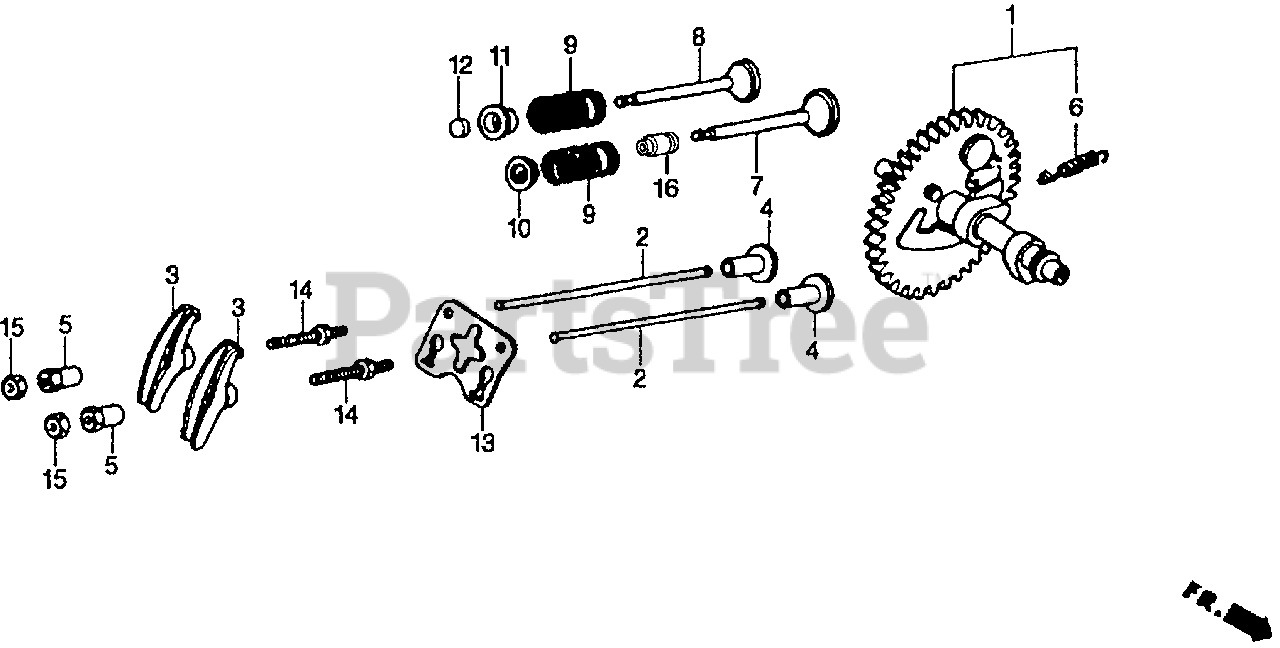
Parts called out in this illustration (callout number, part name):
1	CAMSHAFT ASSY.
2	ROD, PUSH
3	ARM, VALVE ROCKER
4	LIFTER, VALVE
5	PIVOT, ROCKER ARM
6	SPRING, WEIGHT RETURN
7	VALVE, IN.
8	VALVE, EX.
9	SPRING, VALVE
10	RETAINER, IN. VALVE SPRING
11	RETAINER, EX. VALVE SPRING
12	ROTATOR, VALVE
13	PLATE, PUSH ROD GUIDE
14	BOLT, PIVOT (8MM)
15	NUT, PIVOT ADJ.
16	SEAL, VALVE STEM
